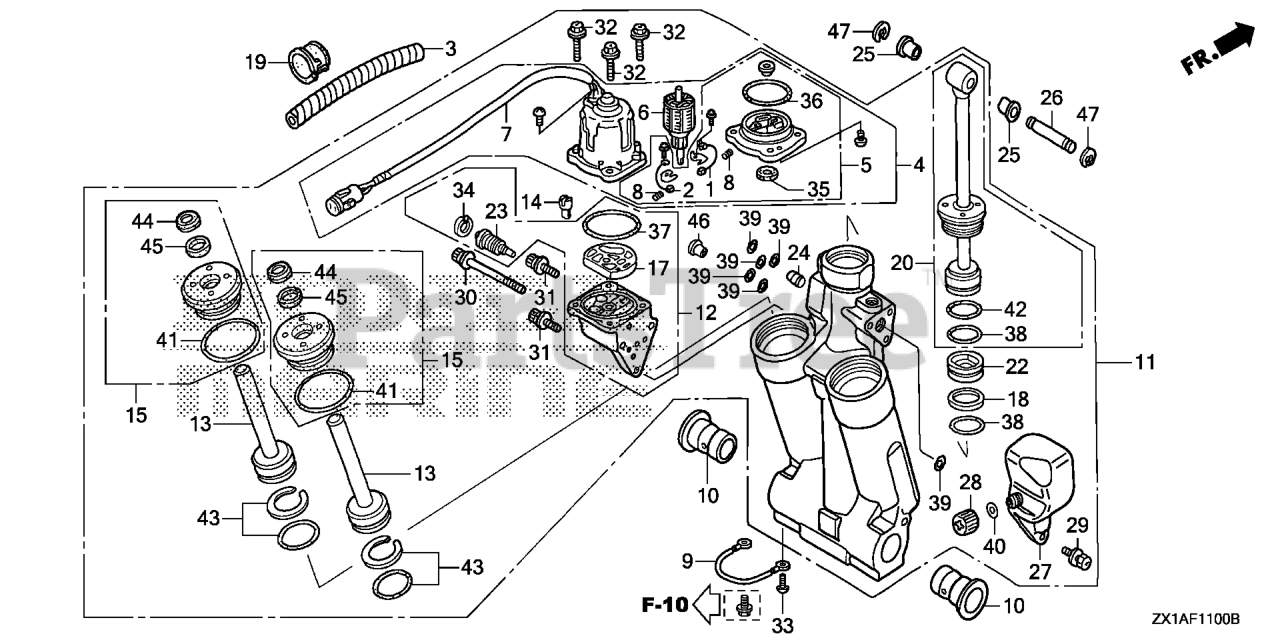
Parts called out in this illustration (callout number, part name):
1	BREAKER ASSY.
2	BRUSH ASSY.
3	TUBE, SPIRAL
4	MOTOR ASSY., POWER TILT
5	BRACKET ASSY.
7	YOKE ASSY.
8	SPRING, MOTOR
9	WIRE, LEAD (1.5X116MM)
10	BUSH, SWIVEL CASE
11	TRIM-TILT, POWER
11	TRIM-TILT ASSY., POWER
12	PUMP ASSY.
13	ROD, PISTON (B)
14	JOINT, DRIVE
15	GUIDE, ROD
16	GUIDE, ROD
17	FILTER (B)
18	RING, BACK-UP
19	BUSH, MOTOR CODE
20	ROD, PISTON
21	ROD, PISTON
22	PISTON, FREE
23	VALVE, MANUAL
25	BUSH, CYLINDER (LOWER)
26	PIN, CYLINDER (UPPER)
27	TANK, OIL
28	CAP, OIL TANK
29	BOLT, RECESSED
31	BOLT B, SOCKET
32	BOLT, HEX.
33	SCREW, PAN (6X8)
34	CIRCLIP (INNER)
36	O-RING (2.0X70.5)
37	O-RING (1.8X69.6)
38	O-RING (3.5X38.7)
39	O-RING (1.68X7.25)
40	O-RING (1.9X11)
41	O-RING (3.5X35.7)
42	O-RING (3.5X41.7)
43	O-RING SET (3.5X31.7)
44	SEAL, WATER
47	E-RING (15MM)
